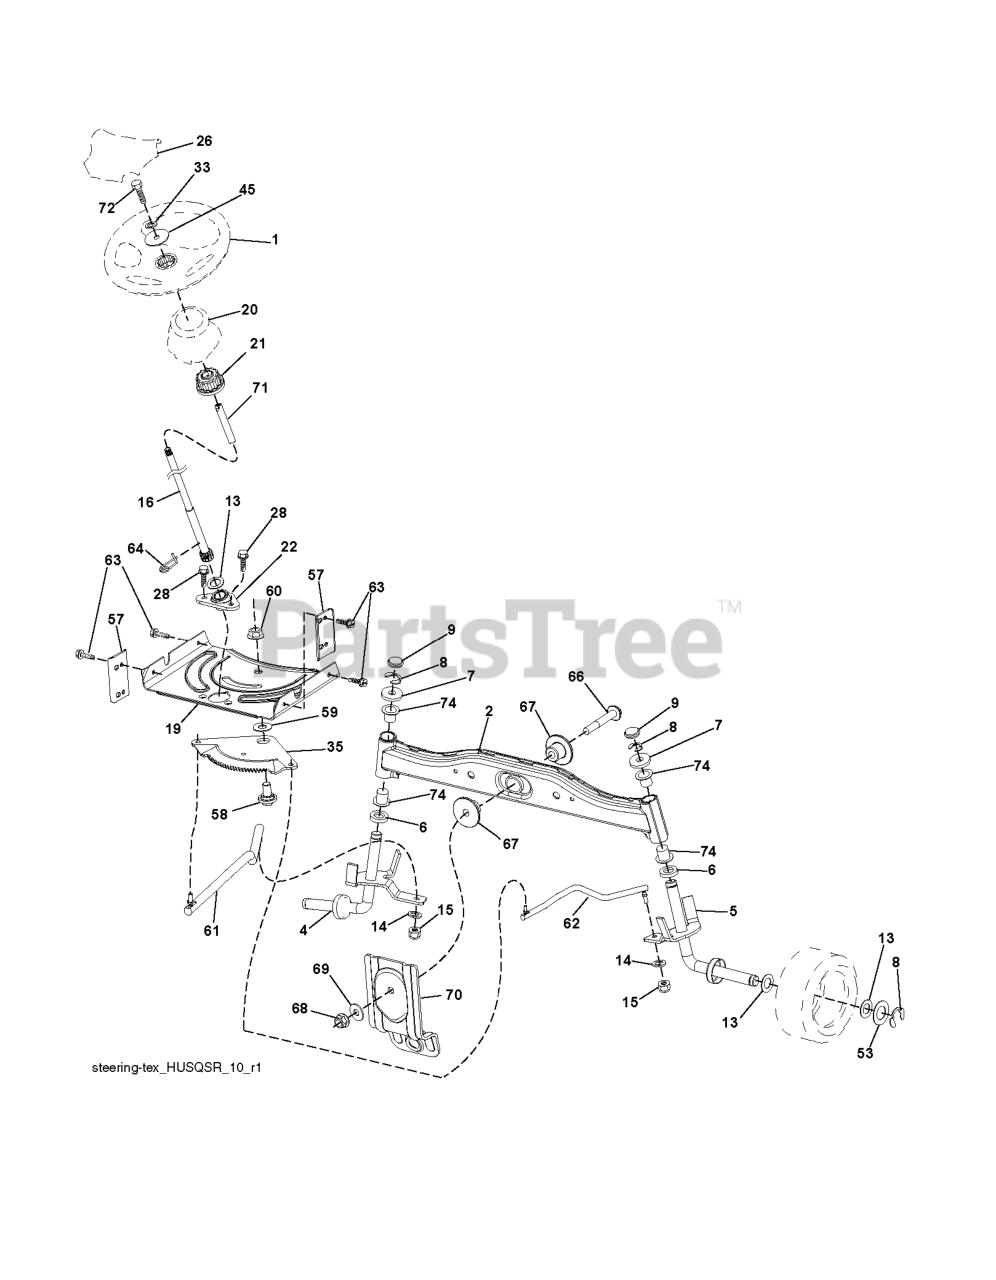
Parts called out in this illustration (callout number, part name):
1	RP WHEEL.STEER.HUSQ.PREM.OVMLD
2	AXLE HALF ASM-WELDED
4	SPINDLE.WELDED.LH.15"TEX
5	SPINDLE.WELDED.RH.15"T
6	THRUST WASHER
9	CAP.SPINDLE.BLACK
14	WASHER, LOCK 3/8
15	NUT CROWNLOCK 3/8-24
16	SHAFT.STEER.3/4.PLATED.TEX
19	PLATE.STEER.DDL.NLT/NG
20	BOOT, STEERING
21	ADAPTER, WHEEL STNG..
22	STEERING.SUPT.LOWER.
26	RP INSERT.CAP.WHL.STRG.HUSQ.
28	SCREW, 3/8-16X3/4
33	WASHER.LOCK.HVY.HLCL.SPR.5/16
35	GEAR.SECTOR.PLATE.DDL.
45	WASHER.11/32
53	WASHER.HARDENED
57	BRACKET.UPSTOP.TEX
58	BOLT.SHOULDER.SECTOR.P
59	WASHER.THURST.SECTOR.S
60	NUT FLANGE LOCK 5/8-11
61	DRAGLINK.LH.BALLSTUD.D
62	DRAGLINK.RH.BALLSTUD.D
63	SCREW
64	RETAINER.CLIP.SPRING.S
66	BOLT HEX FGHD 7/16-14 X 3 SERR
67	BUSHING.PM.FRONT AXLE
68	NUT.LOCK.FLANGE.7/16
69	WASHER.1.5X.505X.118
70	BRKT.DECK.SUSPENSION.F
71	SHAFT.EXTEN.STRG.SPLINE
72	BOLT 5/16-18 X 4 W/PATCH
74	BRNG T
